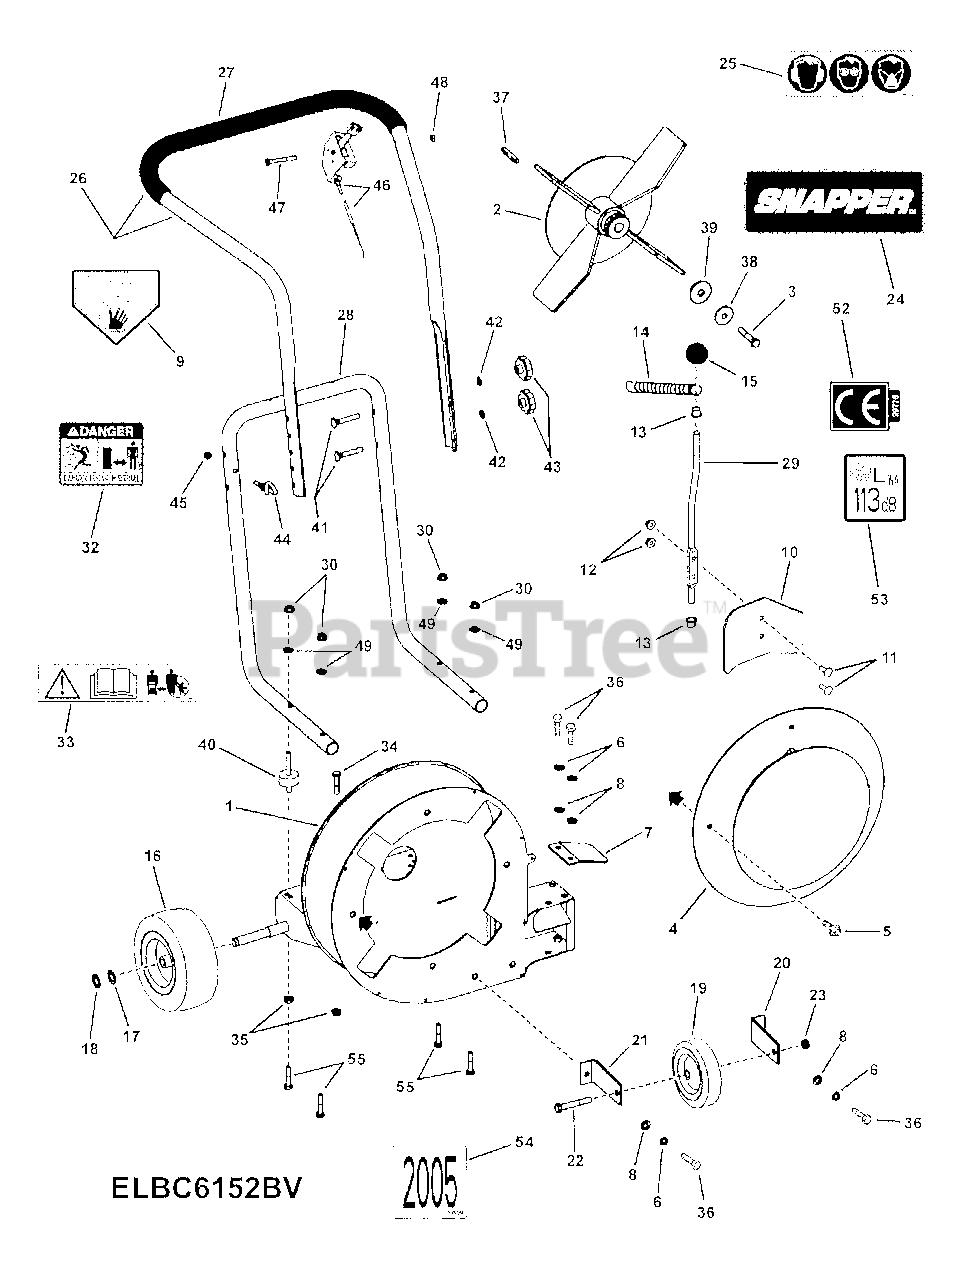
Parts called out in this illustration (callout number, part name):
1	WELDMENT, Base & Housing, 52 Classic
2	WELDMENT, Steel Impeller, 4 Blade, 15.00 O.D.
3	SCREW, 3/8-24 x 2" Hex Head Cap, GR 5
4	WELDMENT, Intake Baffle
5	BOLT, 5/16-18 x 1/2" Hex Flange Lock
6	WASHER, 5/16" Split
7	DEFLECTOR, Side Air
8	WASHER, .34 x .69 x .08 Flat
9	DECAL, Danger, Cut Finger (Euro)
10	DOOR, Forward Air Control
11	BOLT, 1/4-20 x 3/4" Short Square Neck, GR 5
12	NUT, 1/4-20 Hex Flange Lock, GR 5
13	BEARING, 3/8 Clip
14	SPRING, Extension
15	KNOB, #230 Dimco (3/8-16 thread)
16	*ASSY, Wheel & Tire, Sawtooth 4.10/3.50-4 Kenda
17	WASHER, .64 x .99 x .05 Flat
18	RING, External Retaining
19	WHEEL, 6.00 x 1.50 Semi-Pneumatic
20	BRACKET, Caster- RH
21	BRACKET, Caster- LH
22	SCREW, 3/8-16 x 2-1/2" Hex Head Cap, GR 5
23	NUT, 3/8-16 Hex Center Lock, GR 5 or B
24	DECAL, SNAPPER (Panel)
25	DECAL, Personal Protection
26	ASSEMBLY, Upper Handle & Grip- Narrow
27	GRIP, 1.0 x 21-1/2" Foam
28	HANDLE, Lower Folding, Narrow, Blower
29	ROD, Door Front/Side Discharge
30	NUT, 5/16-18 Hex Nyloc
32	DECAL, Danger, Thrown Objects
33	DECAL, Caution, Symbols
34	SCREW, 5/16-18 x 1-1/2" Hex Head Cap, GR 5
35	NUT, 5/16-18 Hex Flange Lock, GR 5
36	SCREW, 5/16-18 x 3/4" Hex Head Cap, GR 5
37	KEY, 1/4" Square x 2"
38	WASHER, .411/.406 I.D. Cone
39	WASHER, .468 x 1.625 x .25 Flat
40	MOUNT, Vibration (5/16-18 threads, both ends)
41	BOLT, 5/16-18 x 2" Curved Head Square Neck, GR 2
42	WASHER, 5/16" Internal Tooth Lock
43	KNOB, Folding Handle
44	ROPE GUIDE (1/4-20 thread)
45	NUT, 1/4-20 Hex Center Lock, GR 5 or B
46	THROTTLE CONTROL, B&S, 35.00/1.62
47	SCREW, 1/4-20 x 2" Hex Head Cap, GR 5
48	NUT, 1/4-20 Hex Nyloc
49	WASHER, 5/16" Curved
52	DECAL, Euro Community (CE)
53	DECAL, Sound 113 dB
54	DECAL, 2005 Year of Manufacture
55	SCREW, 5/16-18 x 1-3/4" Hex Head Cap, GR 5
